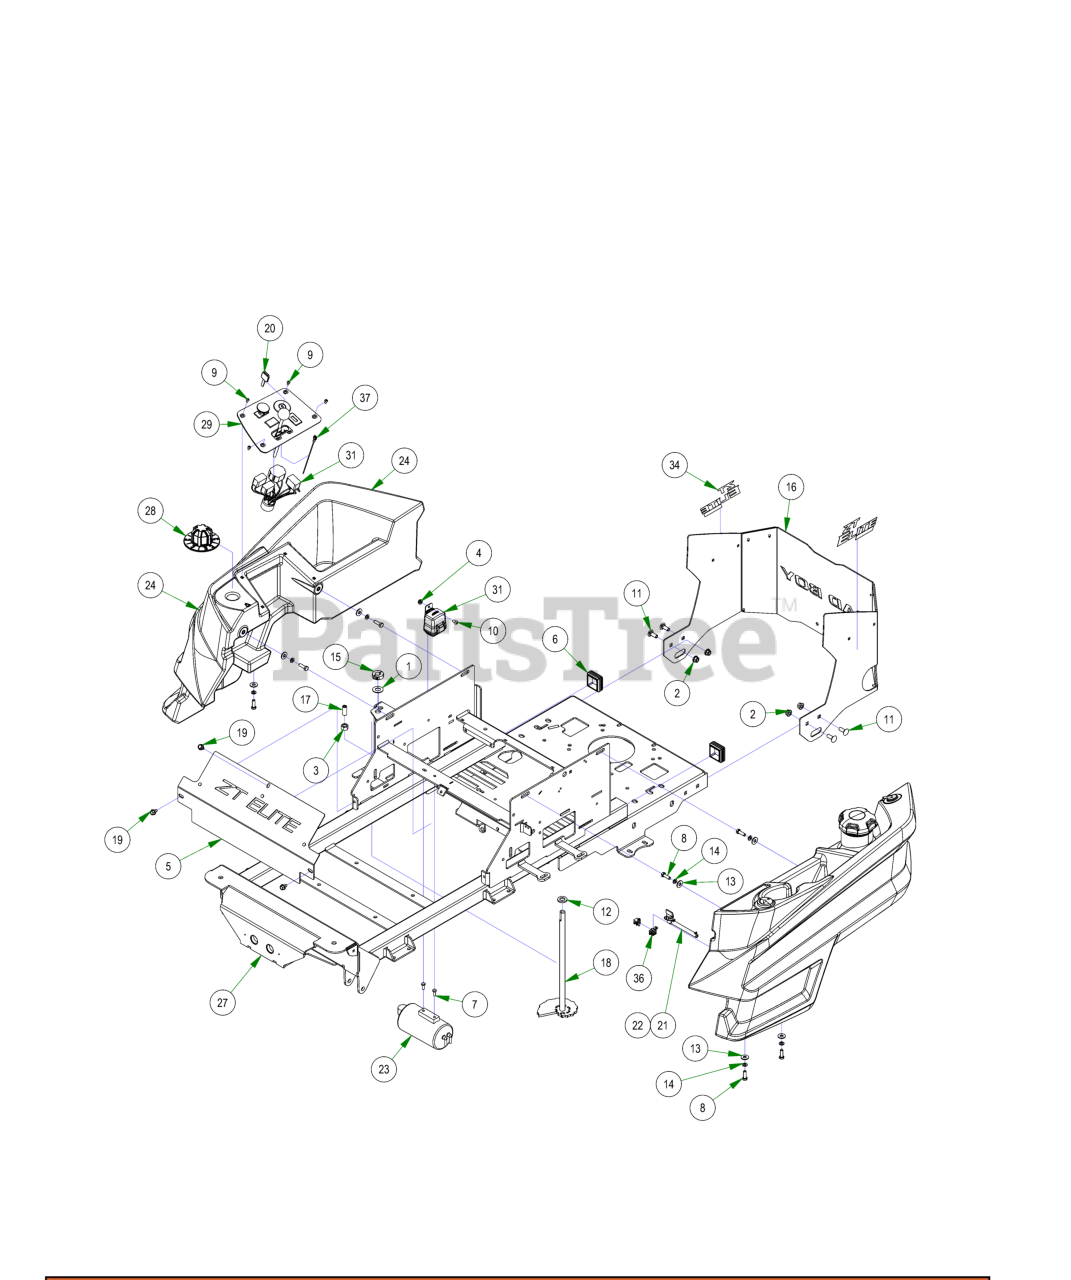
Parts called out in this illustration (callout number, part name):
1	.625 ID x 1.250 OD x .062 THK F/W Nylon
2	3/8-16 NYLON INSERT FLANGE LOCKNUT (GR.F) ZINC
3	1/2-13 HEX NUT ZINC
4	1/4-20 HEX SERRATED FLANGE NUT HARD/ZINC
5	2023 ZT Elite Cooler Cover Assembly
6	2X2 Frame Plug
7	M6-1.0 X 16MM DIN 933 HEX TAP BOLT (CL 8.8) ZINC
8	5/16-18 X 1 HEX CAP SCREW (GR.5) ZINC
9	10-32 X 3/8 BUTTON SOCKET CAP SCREW 18-8 STAINLESS
10	1/4-20 X 1/2 BUTTON SOCKET CAP SCREW 18-8 STAINLESS
11	3/8-16 X 1 CARRIAGE BOLT (GR.5) ZINC
12	.635 ID X 1.120 OD X .140 THICK FLAT WASHER NYLON
13	5/16 USS FLAT WASHER (7/8 OD) ZINC
14	5/16 SPLIT LOCKWASHER ZINC
15	5/8" Split Collar
16	2022 ZT Elite Rear Cover Assembly
17	Dial Rod Plunger
18	ZT Deck Height Bar Assembly
19	5/16-18 X 1/2 HWH unslot (F) tcs zinc
20	Ignition Key
21	15" Fuel Line Assembly
22	37" Fuel Line Assembly
23	ZT/Mav EPA Cannister Assy
24	2021 Maverick Right Side Tank
25	2021 Maverick Left Side Tank
26	Fuel Pick-up for 067-2021-00
27	2024 ZT Elite Frame
28	MZ/ZT Deck Height Dial
29	2023 Control Panel Assembly
30	Throttle Lever Assembly
31	2024 Wiring Harness with Clips
32	Relay Block Cover Replacement Kit
34	ZT Elite Back Plate Decal
35	Edge Clip With Ziptie
36	Edge Clip With Ziptie
37	2017 MZ/ZT/MAV Tach Wire Assy
